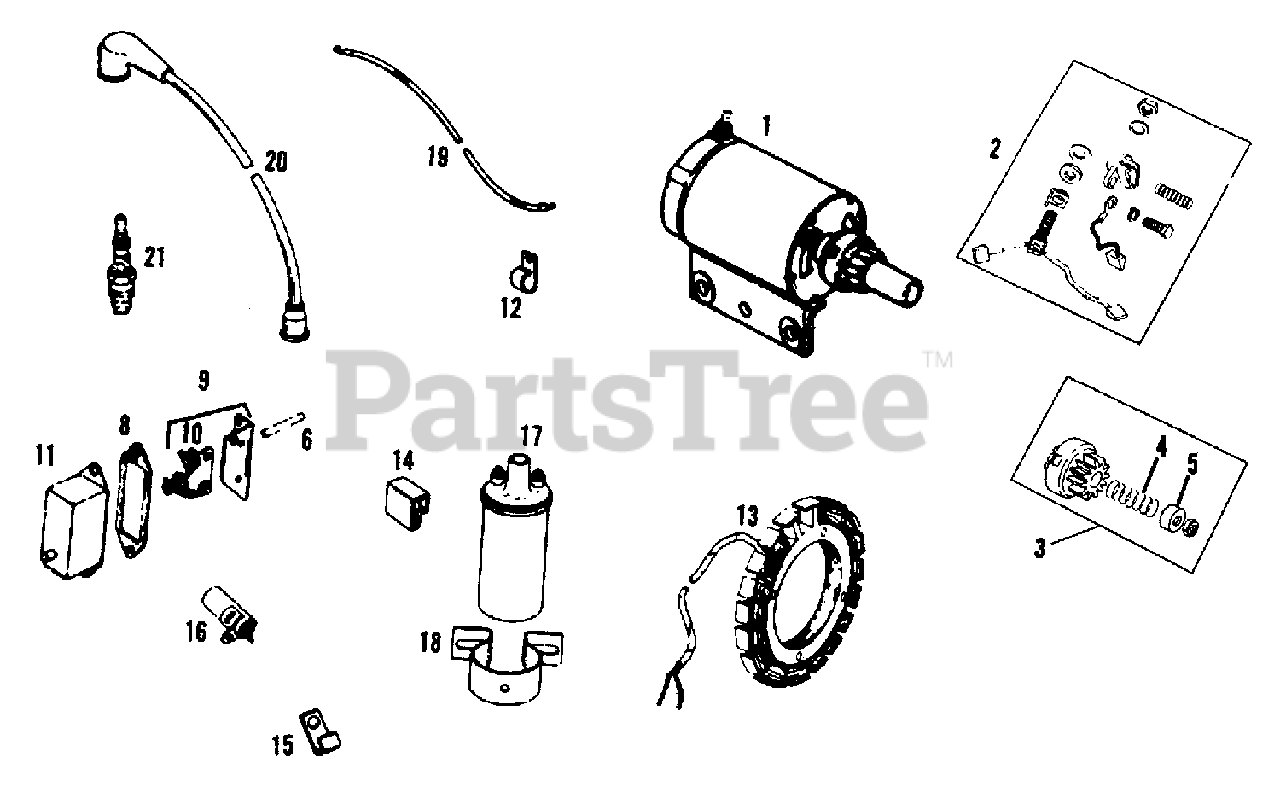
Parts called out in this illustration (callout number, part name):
1	STARTER ASSEMBLY, (Includes Item 2 & 3)
2	KIT, Brush and Spring
3	KIT, Starter Drive (Includes Item 4 and 5)
4	SPRING, Anti-Drift)
5	SPACER, Gear Stop
6	ROD, Breaker
9	BREAKER ASSEMBLY
10	POINT ASSEMBLY, Breaker
14	CONNECTOR
15	CLIP, Cable
16	CONDENSER
19	LEAD, Breaker
20	CABLE, High Tension
21	PLUG, Spark
